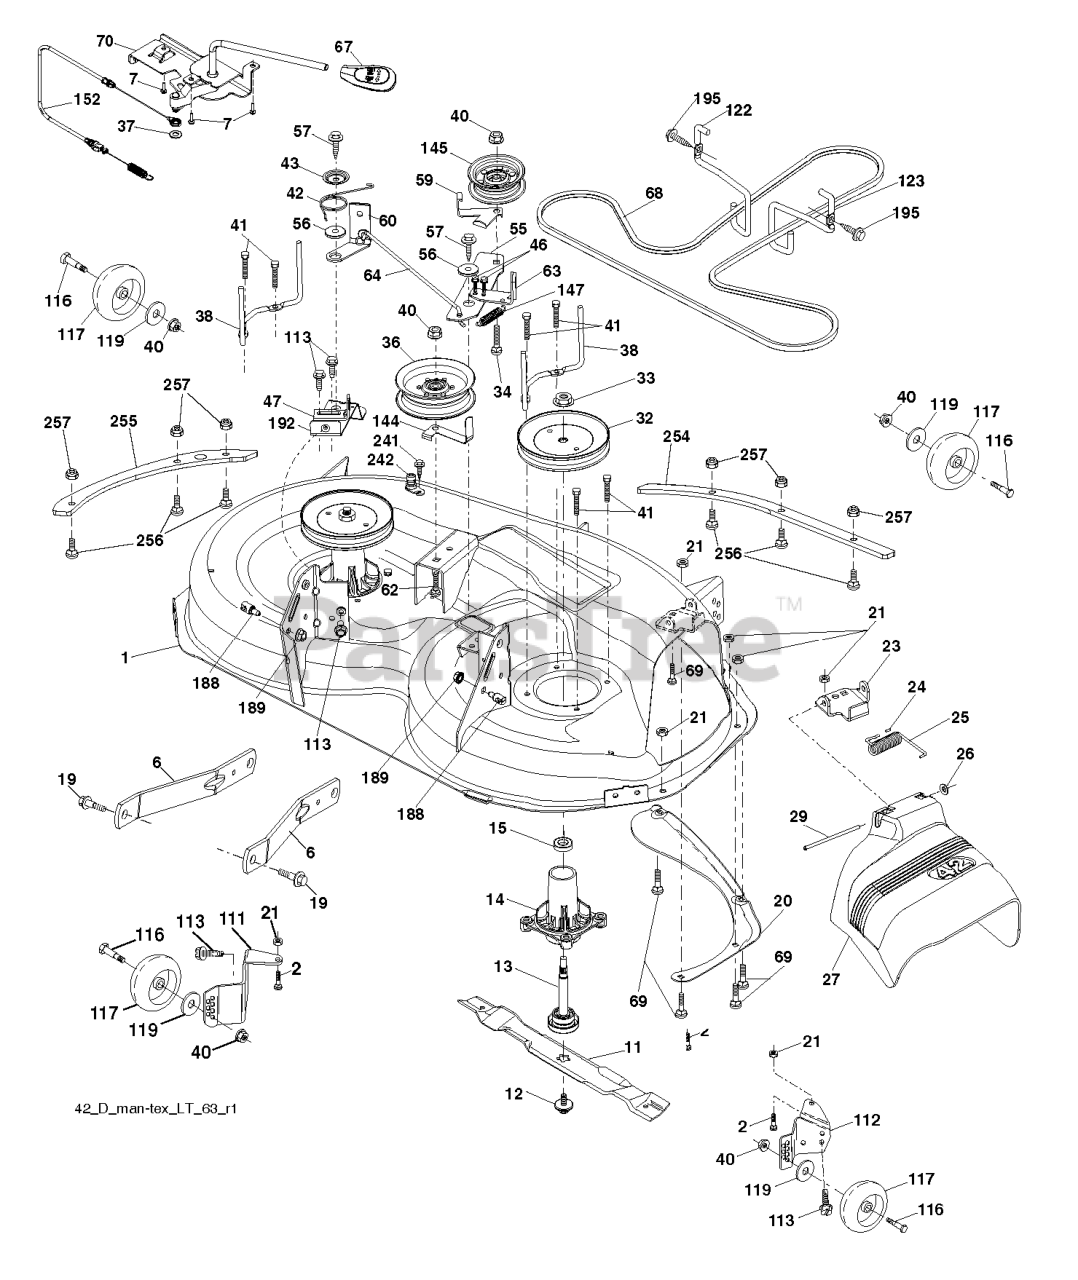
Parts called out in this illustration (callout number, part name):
1	DECK.SVC.42"2GW
2	BOLT 5/16C X 3/4" CARRIAGE
6	ARM.SUSPENSION.MOWER.R
7	SCREW.#10 X 0.750.BOS
11	42" HI-LIFT BLADE
12	SCREW.SEMS.7/16-20X1.HEX.HEAD
13	SHAFT ASM.MNDRL.N/GREASEABLE
14	RP.HOUSING.MANDREL.4PT.
15	BEARING.MANDREL.TOP.EXTENDED
19	BOLT.SHOULDER
20	BAFFLE.VORTEX
21	LOCKNUT
23	BRKT.DEFLECTOR.38"2005+
24	CAP-SLEEVE LT
25	SPRING.TORSION.DEFLECT
26	NUT PUSH M
27	SHIELD.DEFLECTOR.MOWER.42"BLAC
29	ROD.HINGE
32	PULLEY.MANDREL.5.438.PD
33	NUT.FLANGE.LOCK.TOP
34	BOLT.3/8-16X1.50
36	PULLEY.IDLER.2006
37	WASHER
38	KEEPER.BELT.MANDREL.PULLEY
40	NUT LOCK FLG 3/8-16 UNC
41	BOLT.HEX.WASHR.HED.313-18X1.19
42	SPRING.TORSION.BRAKE
43	SRPING.TORSION.RETAINE
46	SCREW.1/4-20X5/8
47	BRKT.CLUTCH.CABLE
55	IDLER.ARM.42"
56	SPACER.RETAINER
57	SCREW 3/8-16X1
59	GUARD, BELT
60	ARM BRAKE MOWER
63	ARM BRAKE MOWER
64	LINKAGE.BRAKE.ASM.ZINC
67	HANDLE.CLUTCH.CABLE.LT
68	BELT.DECK.DRIVE.42"
69	BOLT
70	CLUTCH.ASM.MANUAL.YT.PREDATORQ
111	BRKT.WHEEL.GAUGE.LH.42"
112	BRKT.WHEEL.GAUGE.RH.42"
113	BOLT.5/16HEX.WHS.HD
116	BOLT M
117	WHEEL.GAUGE.RALLY.NARROW
119	WASHER.5/16.FLAT.STE.STD.
122	KEEPER BELT ENGINE LH
123	KEEPER BELT RH
144	KEEPER.BELT.MOWER
145	PULLEY.IDLER.48"PRIMARY
147	RETURN SPRING
152	CABLE.CLUTCH.CABLE.W/SPRING
188	STUD.FASTNER.W/ANTI-ROTATE
189	NUT LOCK HEX FLANGE 5/16-18
192	BRKT.BRAKE.STAND.LH.
195	SCREW, 3/8-16X3/4
241	SCREW.TT.#10-32X.5.3/8.FLANGE
242	PORT.WASHOUT
254	PLATES.RENFRC.42DECK.PT431FRNT
255	PLATES.RENFRCE.42DECK.X431SIDE
256	RHSNB, 1/4-20 X 1, GR5
257	NUT T
